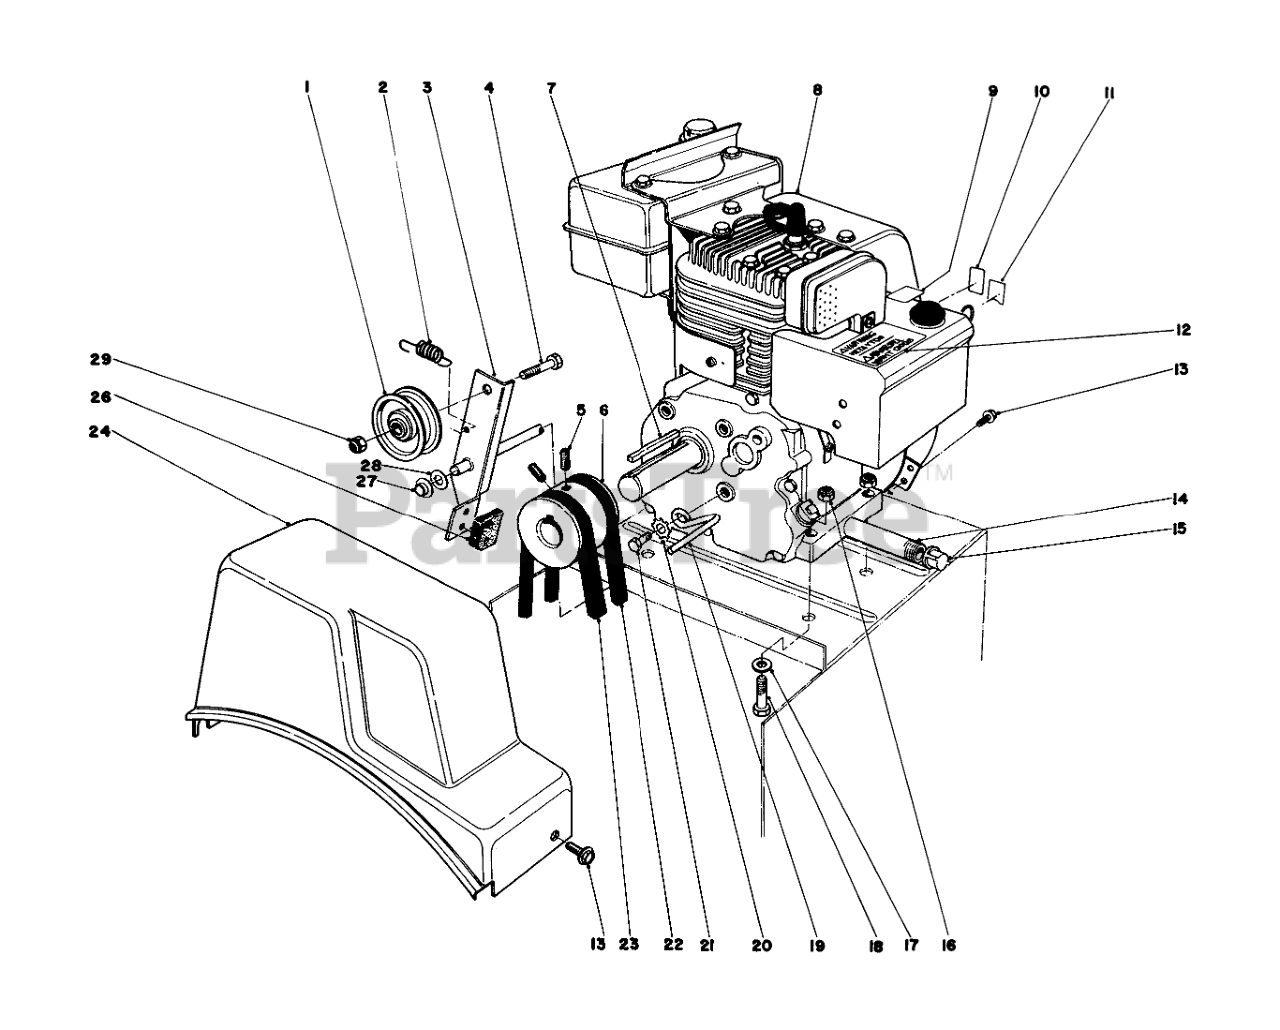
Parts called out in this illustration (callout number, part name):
1	PULLEY-IDLER
2	Spring-Auger Disengage
3	Auger Clutch (Incl. Ref. #26)
4	SCREW-HH
5	Screw-Set
6	ENGINE PULLEY
8	Engine
9	Decal-Primer
10	Decal-Throttle
11	CHOKE DECAL
12	Decal
13	SCREW
14	PIPE NIPPLE
15	CAP-PIPE
16	NUT-LOCK, NI
17	WASHER-PLAIN
18	SCREW-HH
19	RETAINER-BELT
20	WASHER-LOCK
21	SCREW-HH
22	V BELT-3L, TRACTION
23	V-BELT (29.50 INCH)
24	COVER-BELT
26	Brake Pad & Cushion Assy.
27	RETAINER-PUSH ON
28	WASHER-FLAT
29	NUT-LOCK, CONE
